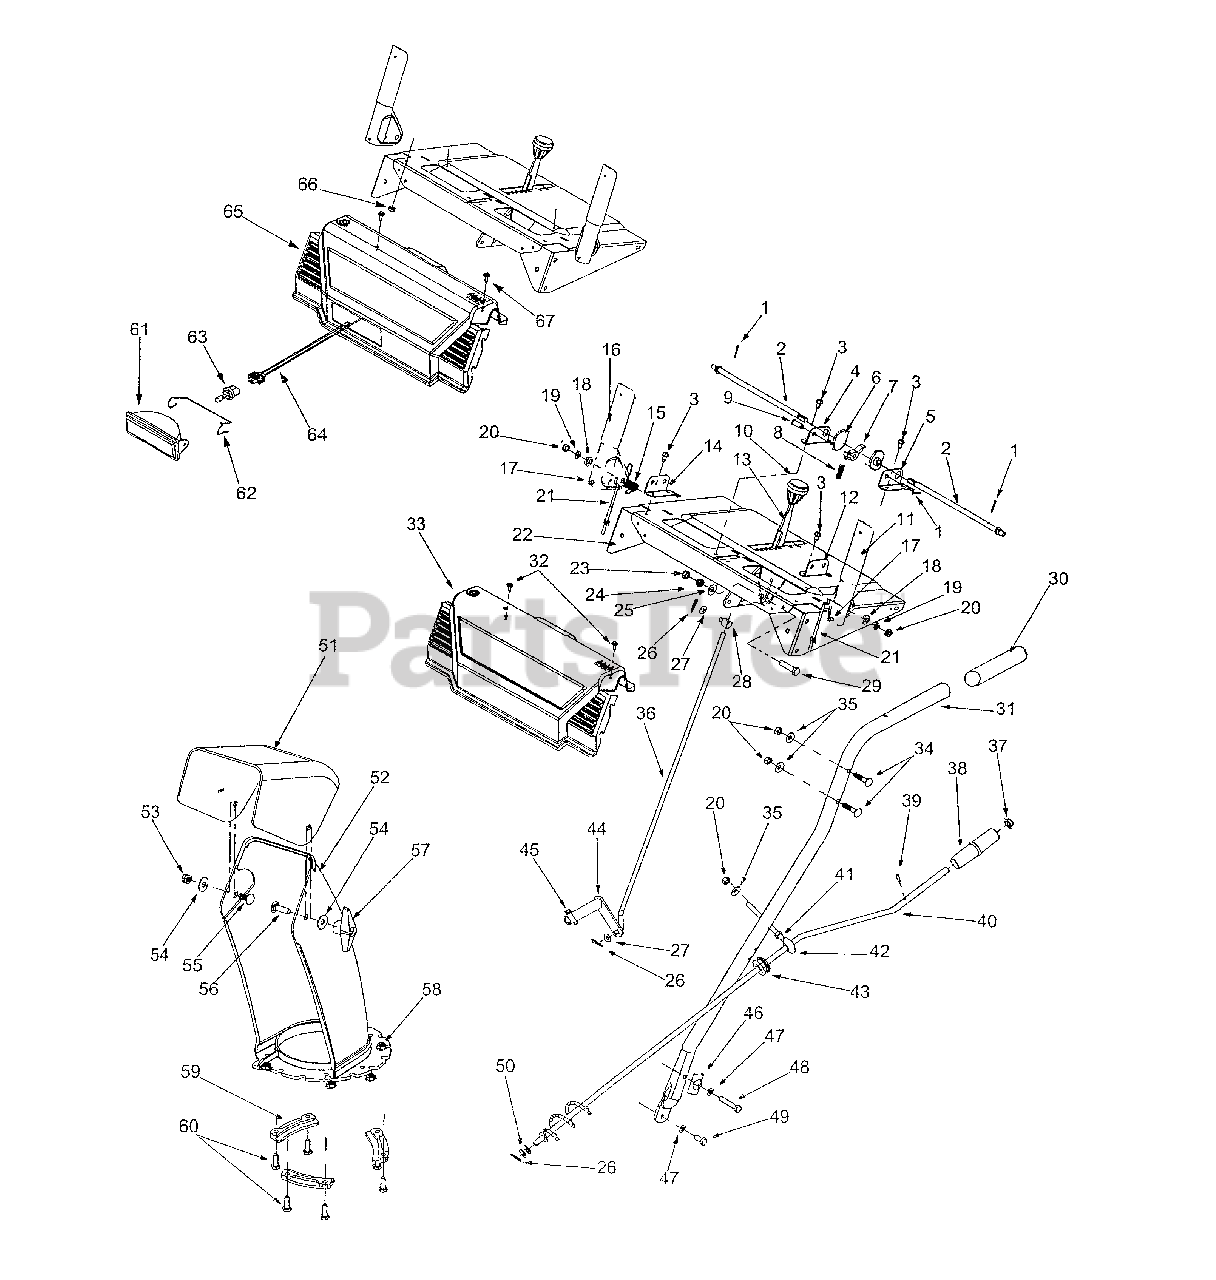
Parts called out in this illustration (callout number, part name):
1	Cotter Pin
3	Hex Washer Screw 1/4-20 x .5
6	Cam Lock Handle
7	Handle Lock Pawl
8	Compression Spring
9	Clevis Pin
10	Knob
11	Handle Assy - LH
15	Torsion Spring
16	Handle Assy - RH
17	Rubber Bumper
19	Lock Washer 5/16
20	Hex Nut 5/16-18
21	Cable
24	Compression Spring
25	Bell Washer
26	Cotter Pin
27	Flat Washer 5/16
28	Ferrule
29	Hex Cap Screw 3/8-24 x 1.50
33	Handle Panel
34	Carriage Bolt 5/16-18 -x I.50
35	Bell Washer.340 ID x .872 OD
38	Chute Knob
39	Roll Pin
40	Chute Crank
41	Hex Nut 5/16 - 18
42	Chute Crank Eyebolt
43	Rubber Grommet
45	Hex Washer Screw 1/4-20 x 1.0
46	Handle Tab
47	Lock Washer 5/16
48	Hex Cap Screw 5/16-18 x 1.75
49	Hex Cap Screw 5/16-18 x .75
50	Flat Washer
51	Upper Chute
52	Lower Chute
53	Hex Lock Nut 5/16-18
54	5/16 Washer
55	Carriage Bolt 5/16-18 x .75
56	Carriage Screw 5/16-18 x 1.0
58	Hex Lock Nut 1/4-20
59	Flange Keeper
60	Hex Cap Screw 1/4-20 x .75
61	Lens Housing Assembly
62	Headlight Retaining Wire
63	Halogen Light
64	Light Harness
65	Panel w/light
66	Hex Nut 1/4-20
67	Hex Washer Screw #10-16 x .625
